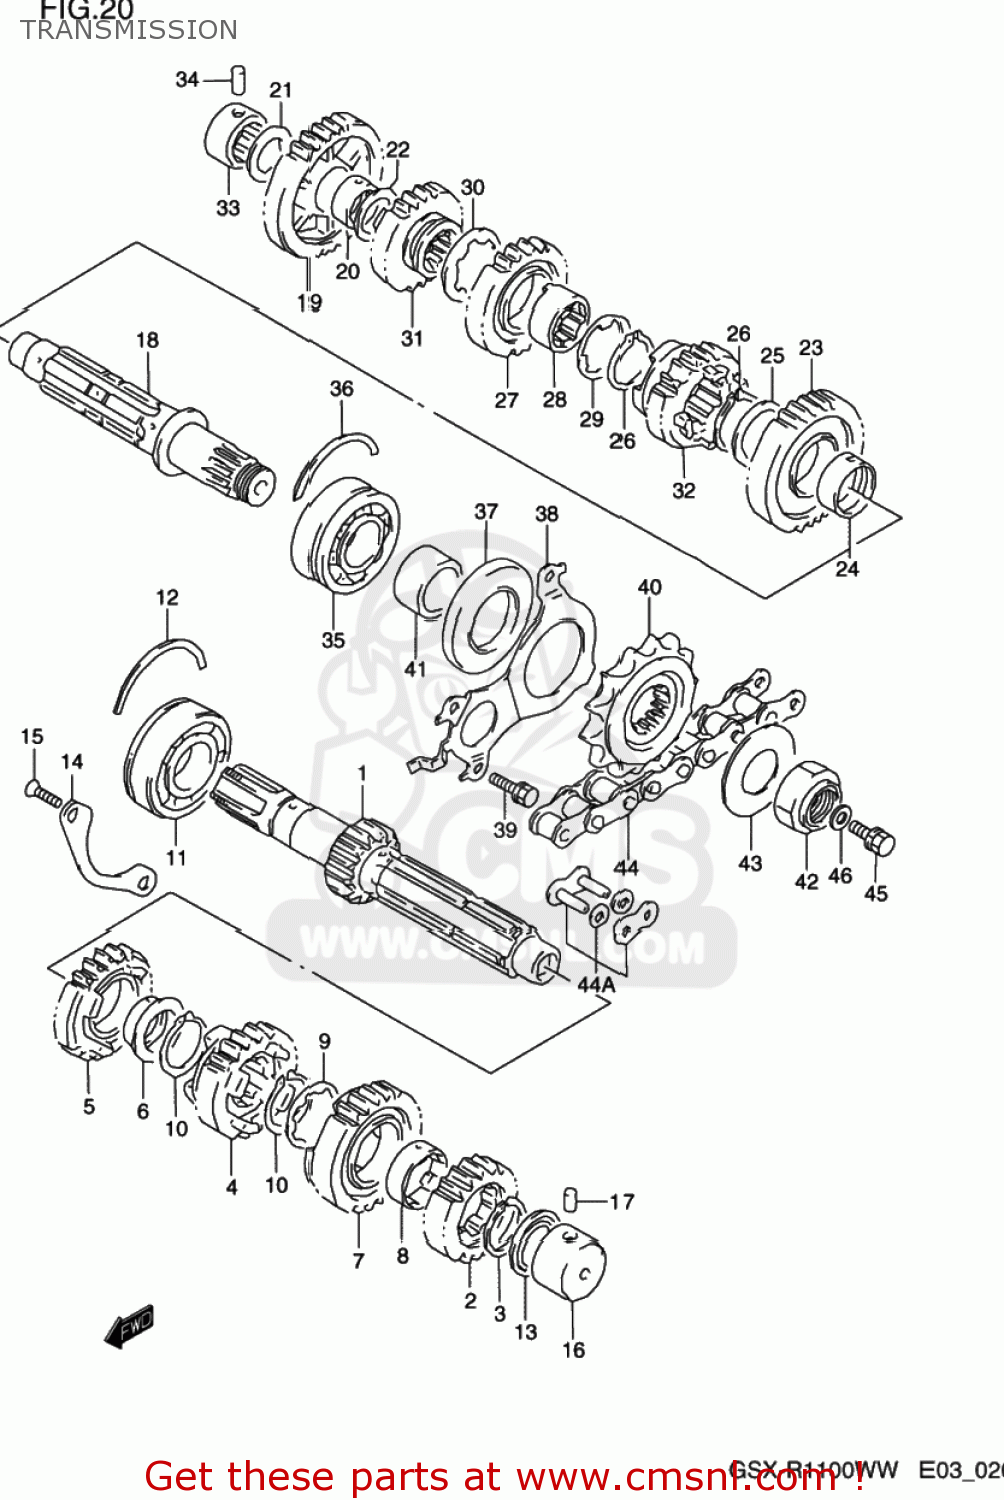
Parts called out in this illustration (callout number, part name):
1	SHAFT COMP,COUNTER
2	GEAR,2ND DRIVE
3	CIRCLIP
4	GEAR,THIRD DRIVE
5	GEAR,FOURTH DRIVE
6	BUSH(28X32X2)
7	GEAR,5TH DRIVE
8	BUSH
9	WASHER,LOCK
10	CIRCLIP
11	BEARING(25X62X17)
12	C RING
13	SEAL,OIL(20X31.2X2.7)
14	RETAINER,CNTR SHAFT BEARING
15	SCREW
16	BEARING
17	PIN
18	SHAFT,DRIVE
19	GEAR,1ST DRIVEN
20	BUSHING
21	WASHER
22	WASHER
23	GEAR,2ND DRIVEN
24	BUSH(28X32X11)
25	SHIM(28X38X1)
26	CIRCLIP
27	GEAR,3RD DRIVEN
28	BUSH,3RD DRIVEN GEAR
29	WASHER,LOCK
30	WASHER,LOCK
31	GEAR,4TH DRIVEN
32	GEAR,5TH DRIVEN
33	BEARING(20X34X20)
34	PIN
35	BEARING(28X70X18)
36	C RING
37	SEAL,OIL(34.8X70X6)
38	RETAINER,DRIVE SHAFT OIL SEAL
39	BOLT
40	SPROCKET,ENGINE(15T)
41	SPACER(25X36X17.7)
42	NUT
43	WASHER,THRUST
44	CHAIN,DRIVE(116LE)
44A	JOINT SET
45	BOLT
46	WASHER
